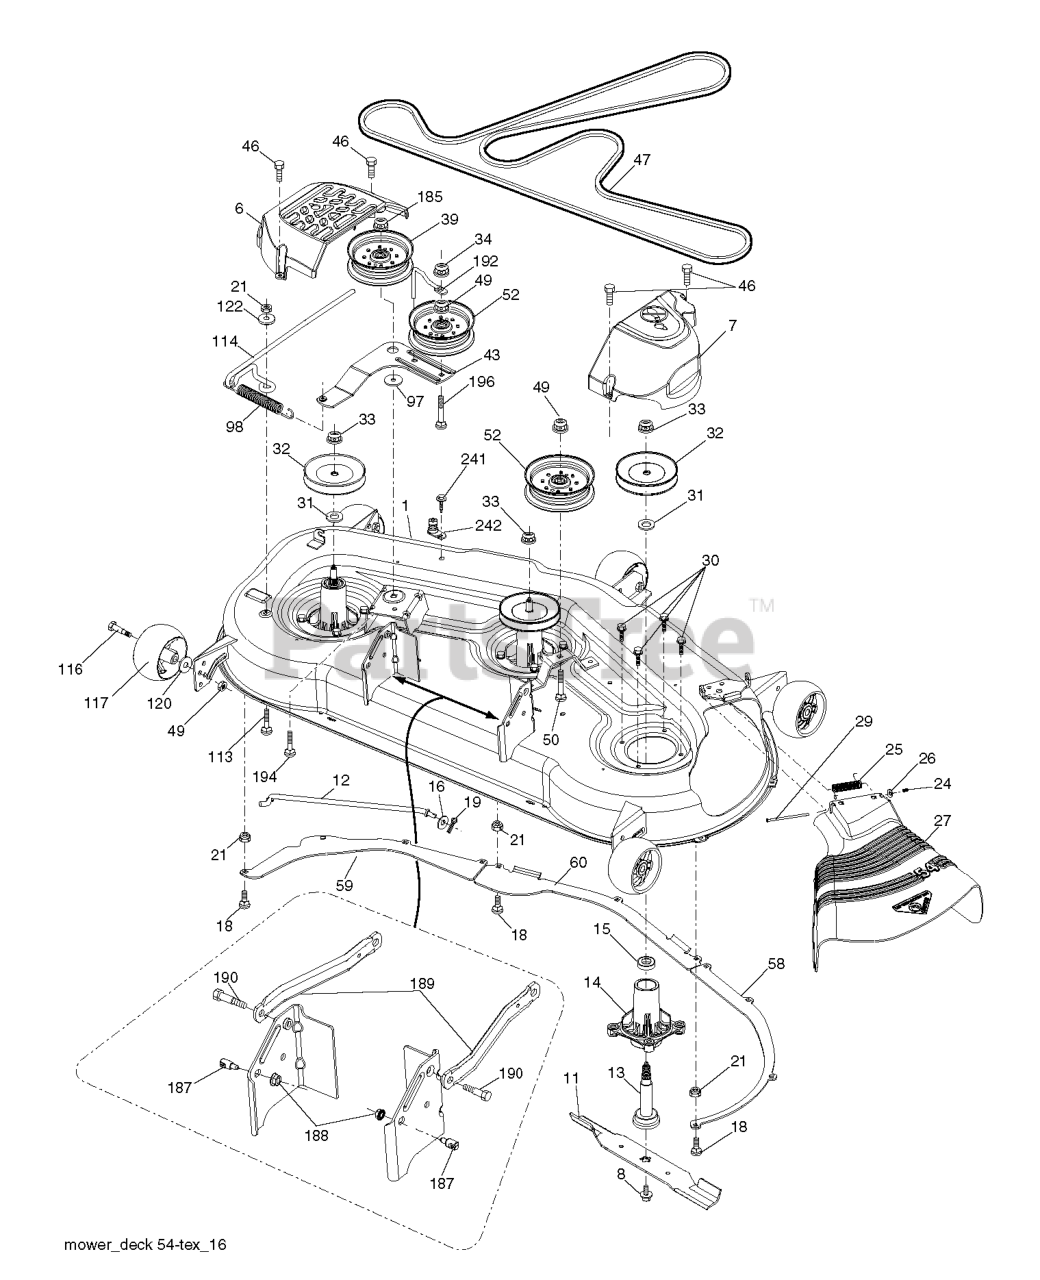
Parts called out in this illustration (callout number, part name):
1	DECK.WELDMENT.54"MS418
6	COVER.MANDREL.LH.54"20
7	COVER.MANDREL.RH.54.20
8	BOLT.WASHER.ASM.7/16-2
11	54" MULCH BLADE
11	BLADE.BAGGING.54"
12	ROD.ANTI.SWAY.48/54"K4
13	SHAFT ASM MANDREL
14	RP.HOUSING.MANDREL.4PT.
16	WASHER
18	BOLT
19	PIN.COTTER.5/16.BOW TI
21	LOCKNUT
24	CAP-SLEEVE LT
25	SPRING, TORSION
26	NUT PUSH M
27	DEFLECTOR
29	ROD.HINGE
30	SCREW, WASHER HEAD
31	WASHER.SPACER.MANDREL
32	PULLEY/MANDREL
33	NUT.FLANGE.LOCK.TOP
39	RB PULLEY.IDLER.4.50/HUB SPEC
43	ARM.IDLER
46	SCREW.1/4-20X5/8
47	RP.BELT.DRIVE.54."2006
49	NUT LOCK FLG 3/8-16 UNC
50	BOLT
52	PULLEY.IDLER.2006
58	BAFFLE.RIGHT.54"
59	BAFFLE.LEFT.54"
60	BAFFLE CENTER 54" MOWER
98	SPRING, DECK DRIVE
113	BOLT CRT
114	ROD TENSION RELIEF
116	BOLT.SHOULDER.3/8-16X3-5/8.
117	RP WHEEL. GUAGE RALLY
120	WASHER
122	BUSHING.RELIEF.TENSION
185	NUT.LOCK.FLANGE.7/16
187	STUD.FASTNER.W/ANTI-ROTATE
188	NUT LOCK HEX FLANGE 5/16-18
189	ARM.SUSPENSION.MOWER
190	BOLT.SHOULDER
192	KEEPER.BELT.IDLER.54"T
194	BOLT.HEX.WASHER.HEAD.7/16-24X
196	BOLT
241	SCREW.TT.#10-32X.5.3/8.FLANGE
242	PORT.WASHOUT
